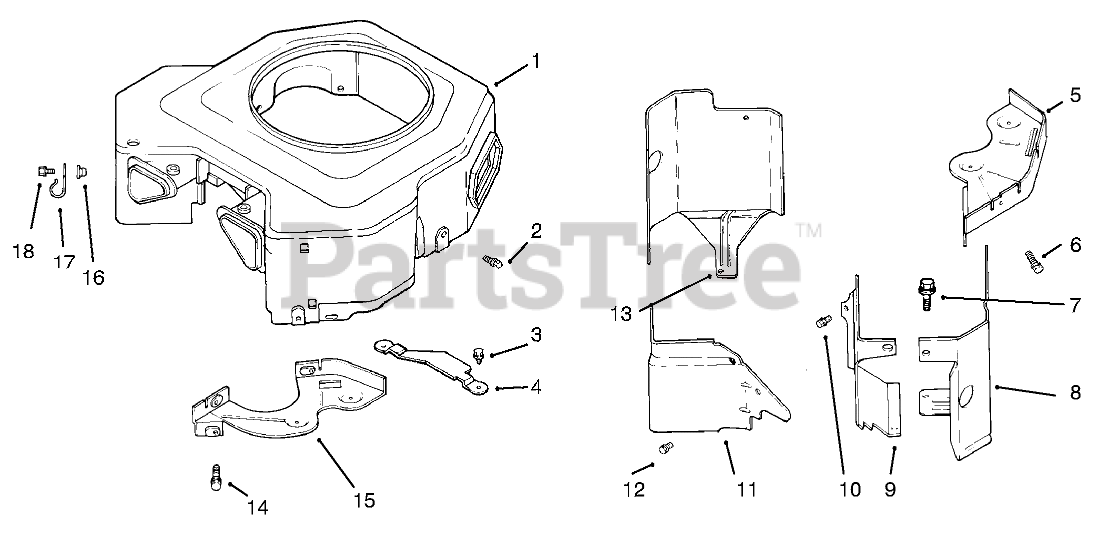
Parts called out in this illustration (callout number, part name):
1	Blower Housing ASM
2	Screw
3	Screw
4	Guard-Flywheel
5	Plate-Backing #2 Side
6	Screw
7	Screw
8	Baffle-Cylinder, #2
9	Baffle-Valley #1 Side
10	Screw
11	Baffle-Valley #2 Side
12	Screw
13	Baffle-Cylinder #1Side
14	Screw
15	Plate-Instruction
16	Nut
17	Clamp
18	Screw
